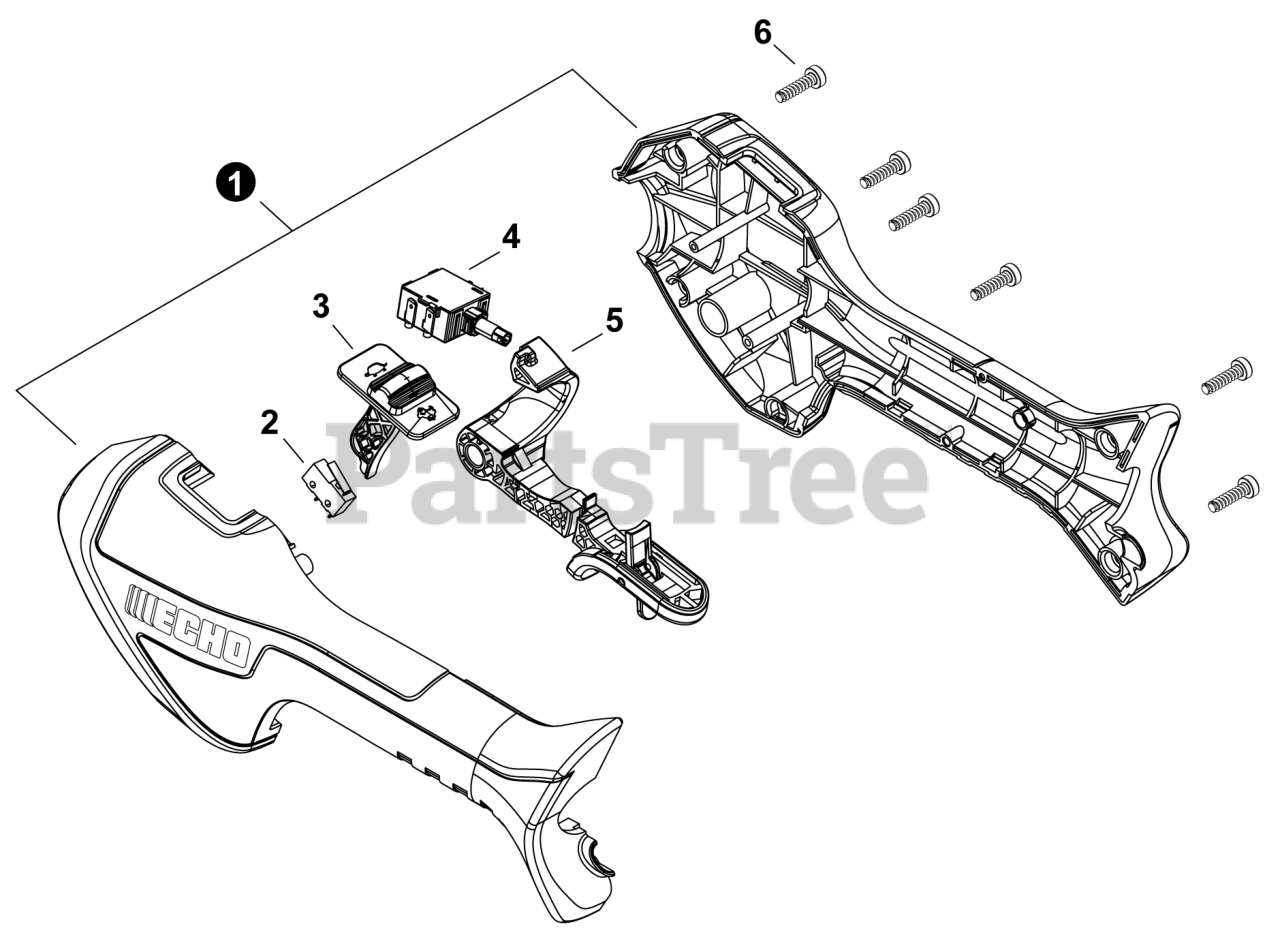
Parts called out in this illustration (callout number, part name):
1	CONTROL HANDLE SET
2	SWITCH, HIGH/LOW MICRO
3	SWITCH, SPEED
4	SWITCH, VARIABLE SPEED
5	TRIGGER ASSY, THROTTLE
6	SCREW - 4x16
